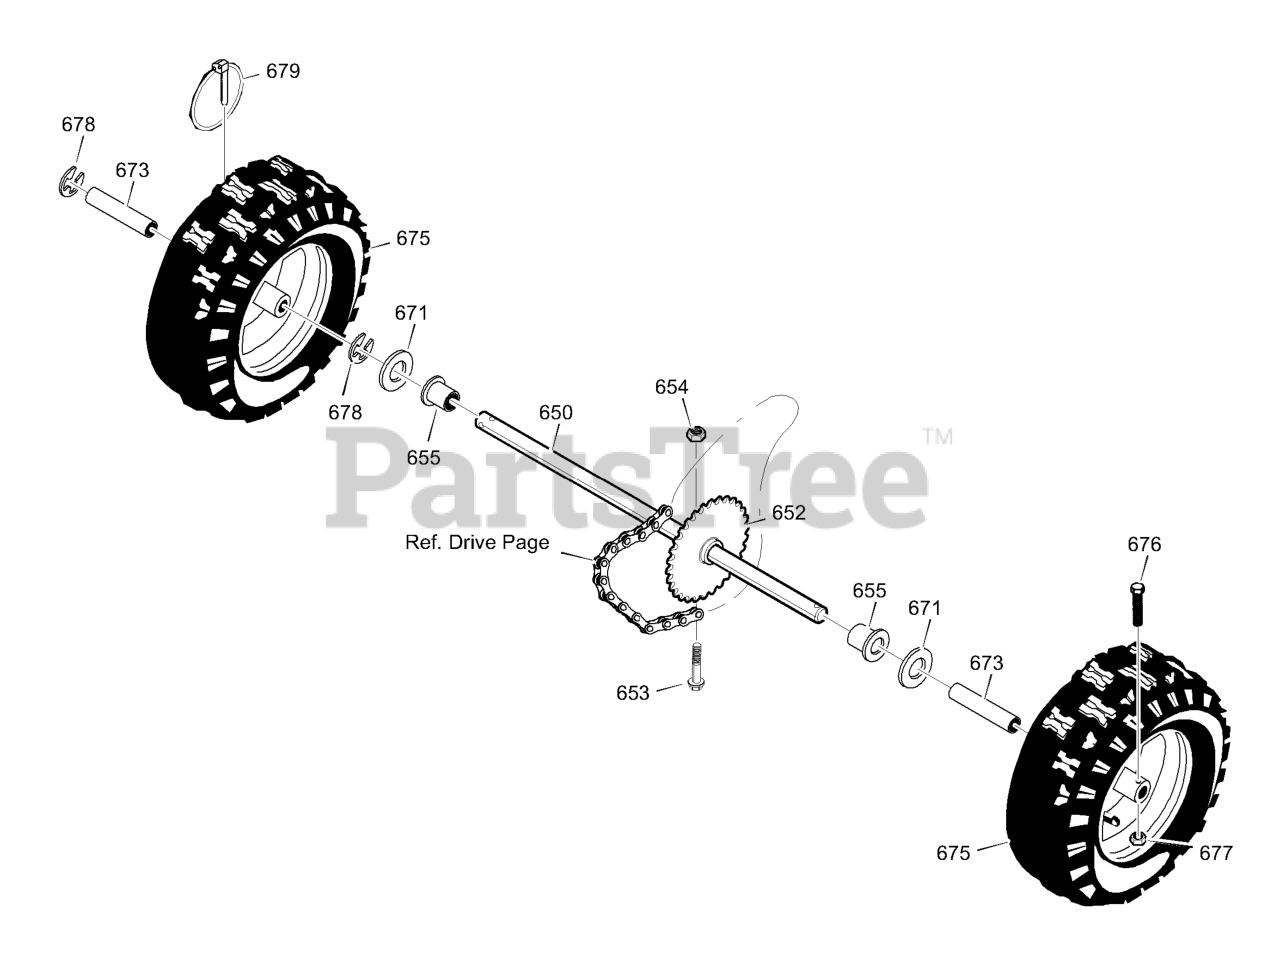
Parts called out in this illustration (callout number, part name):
650	SHAFT, AXLE
652	SPRKT & HUB
653	SCREW, 1/4-20X1.75
654	NUT, 1/4-20 HEX NYLOCK
655	BEARING, AXLE
671	FLATWASHER
673	BUSHING, WHEEL
675	TIRE & RIM
676	SCREW, 1/4-20X1.75 HH
677	NUT, 1/4-20 HEX NYLOCK
678	RING, RET
679	PIN, KLIK .25 X 1.38 DIA
